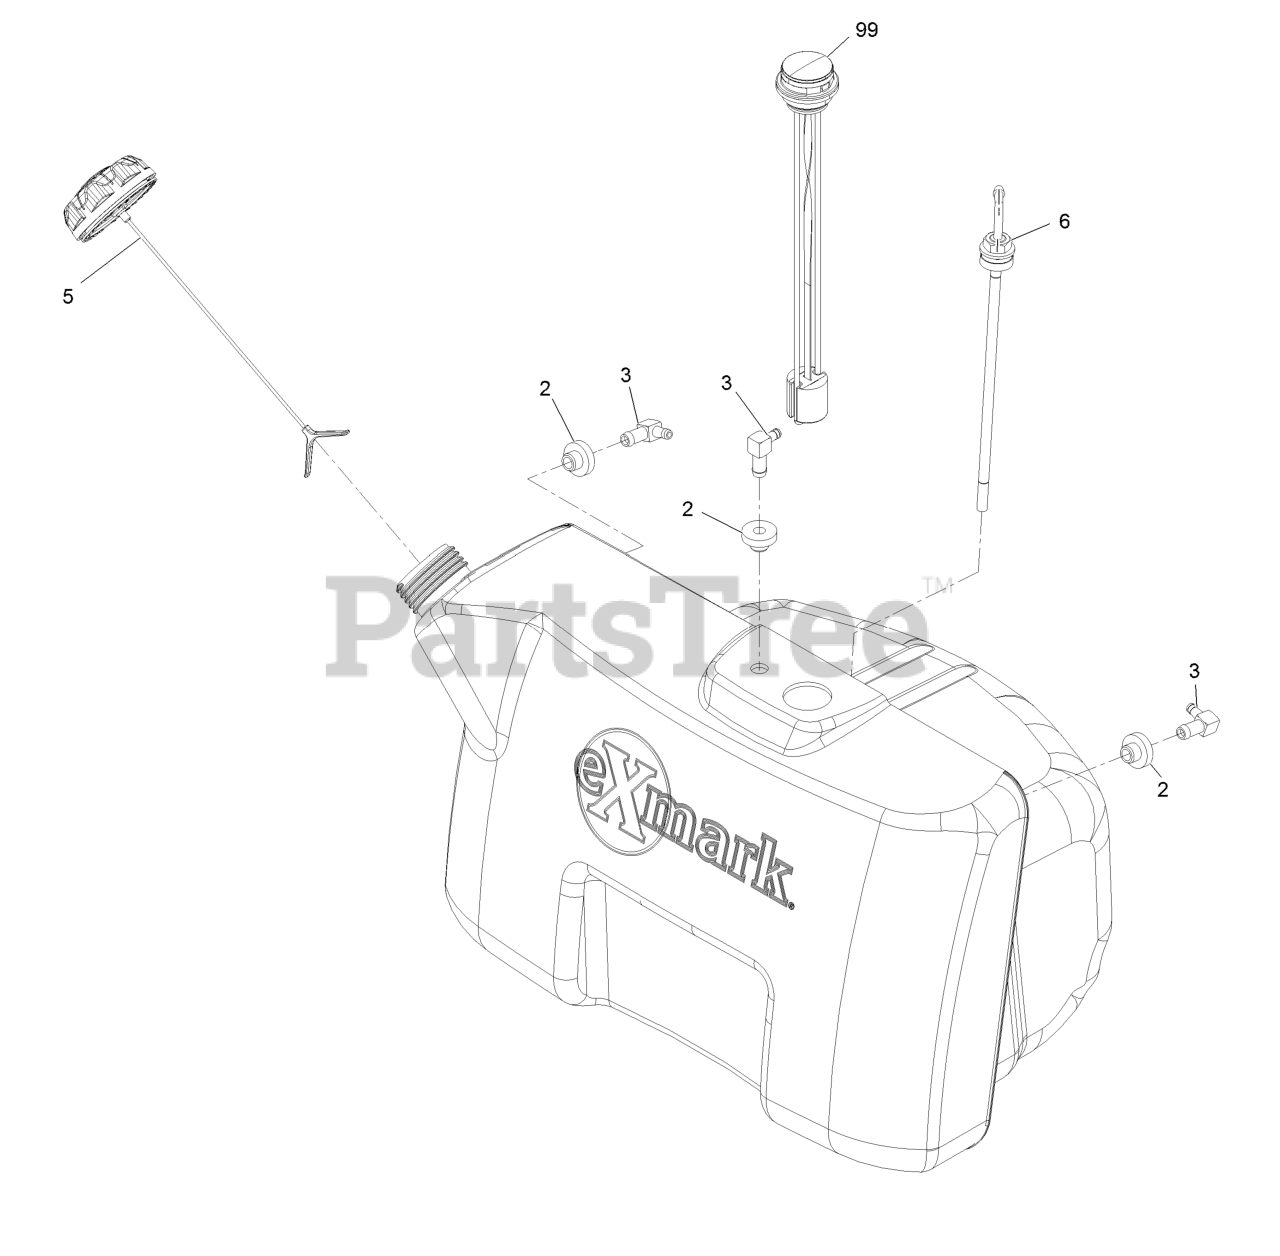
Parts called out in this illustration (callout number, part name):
2	Bushing
3	Elbow-90 DEG
5	Cap-Fuel, Ratcheting
6	Fitting-Fuel, Bulkhead
99	Kit, Fuel Gage Replacement
